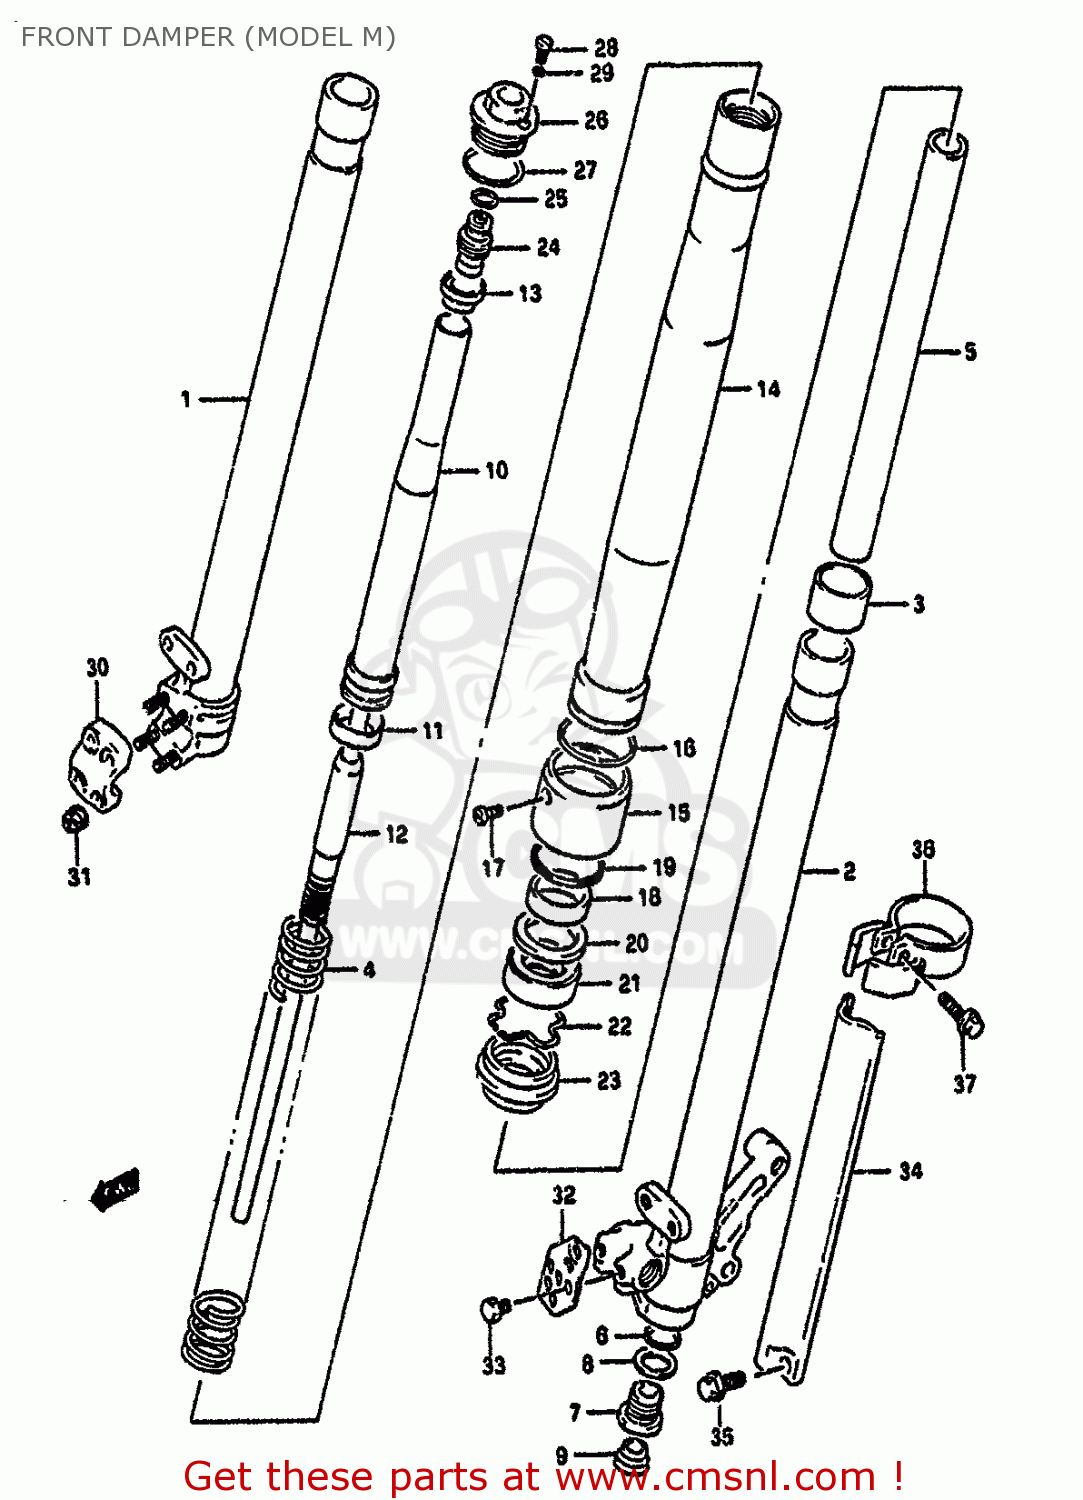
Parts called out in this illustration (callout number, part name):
1	TUBE,INNER,RIGHT
2	TUBE,INNER,LEFT
3	BUSH,SLIDE
4	SPRING,MAIN
5	CYLINDER
6	O-RING
7	BOLT,CENTER
8	GASKET (NAS)
9	CAP
10	SPACER,SPRING
11	RING,PISTON
12	ROD ASSEMBLY,PISTON
13	SEAT,SPRING STOPPER
14	TUBE,OUTER
15	HOLDER,AXLE,R
16	O RING,CASE
17	SCREW
18	BUSH,GUIDE
19	RING,STOPPER,UPPER
20	SPACER,SEAL
21	OIL SEAL,FRONT FORK
22	RING,OIL SEAL STOPPER
23	SEAL,DUST
24	ADJUSTER,SPRING
25	NUT
26	BOLT,FORK
27	O RING
28	BOLT,PLUG
29	O RING, PLUG
30	HOLDER,AXLE,R
31	NUT
32	GUIDE,HOSE,L
33	BOLT, HOSE GUIDE
34	PROTECTOR,FORK,L
35	BOLT,PROTECTOR(6X10)
36	GUIDE,FORK PROTECTOR,R
37	BOLT,PROTECTOR GUIDE
